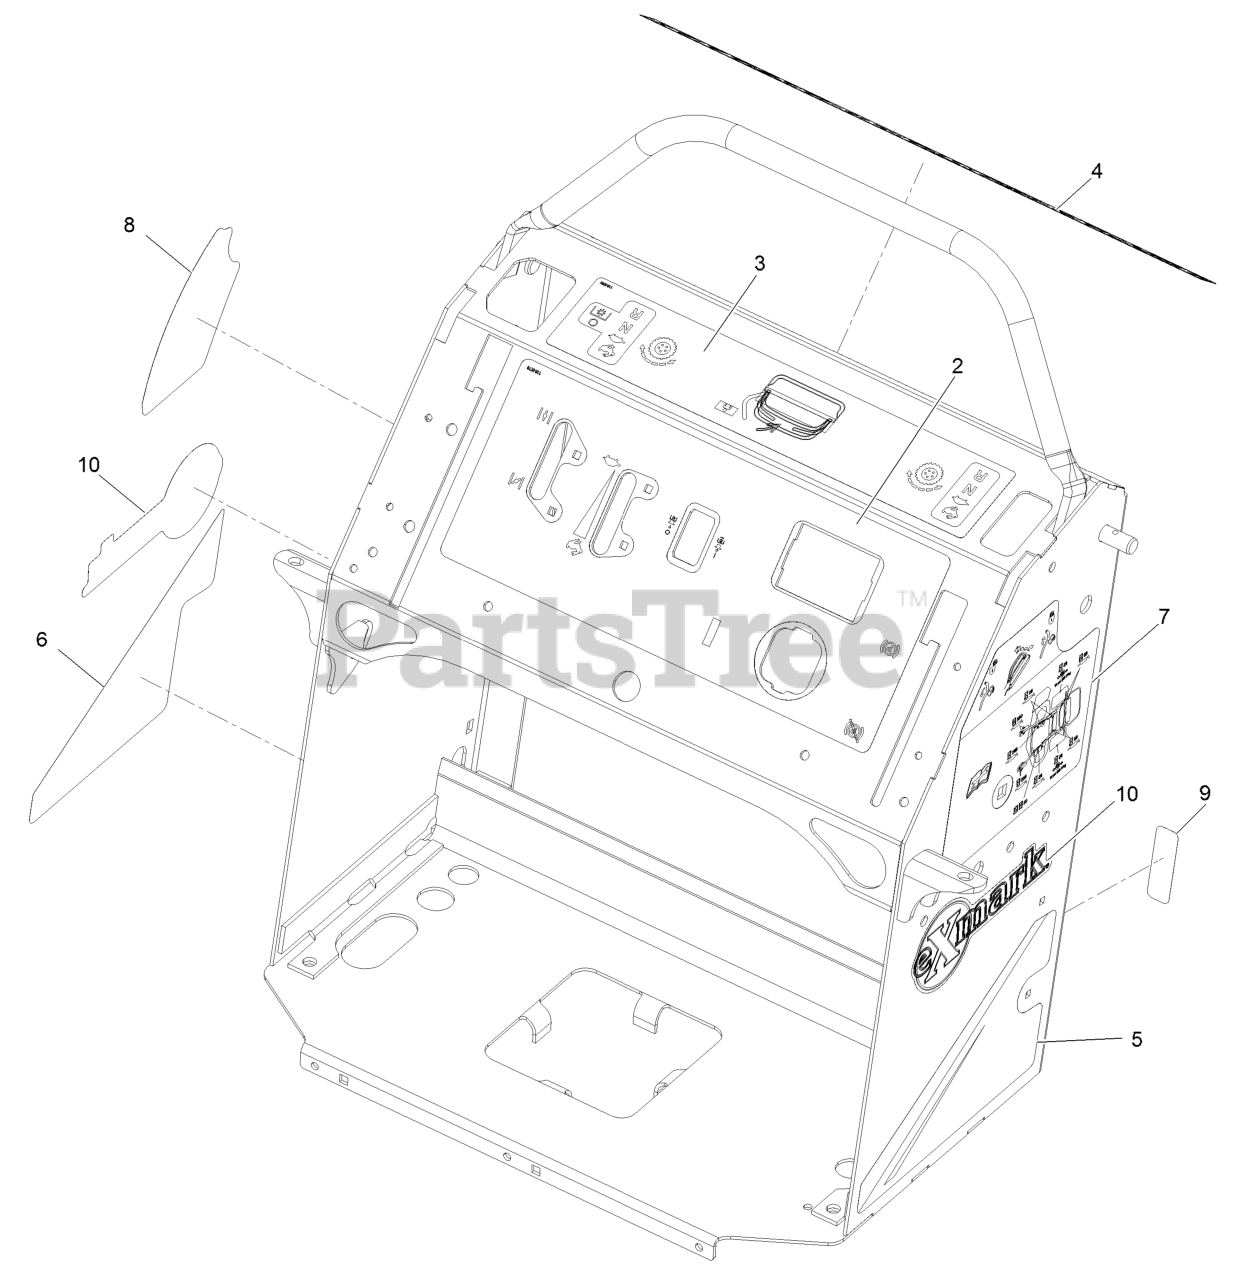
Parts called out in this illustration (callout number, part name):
2	DECAL-CONTROL PANEL
3	DECAL-MOTION CONTROL
4	DECAL-WARNING
5	DECAL-LH PANEL
6	DECAL-RH PANEL
7	DECAL-SERVICE AID
8	DECAL-HEIGHT OF CUT
9	DECAL-FUSE
10	DECAL-EXMARK LOGO
